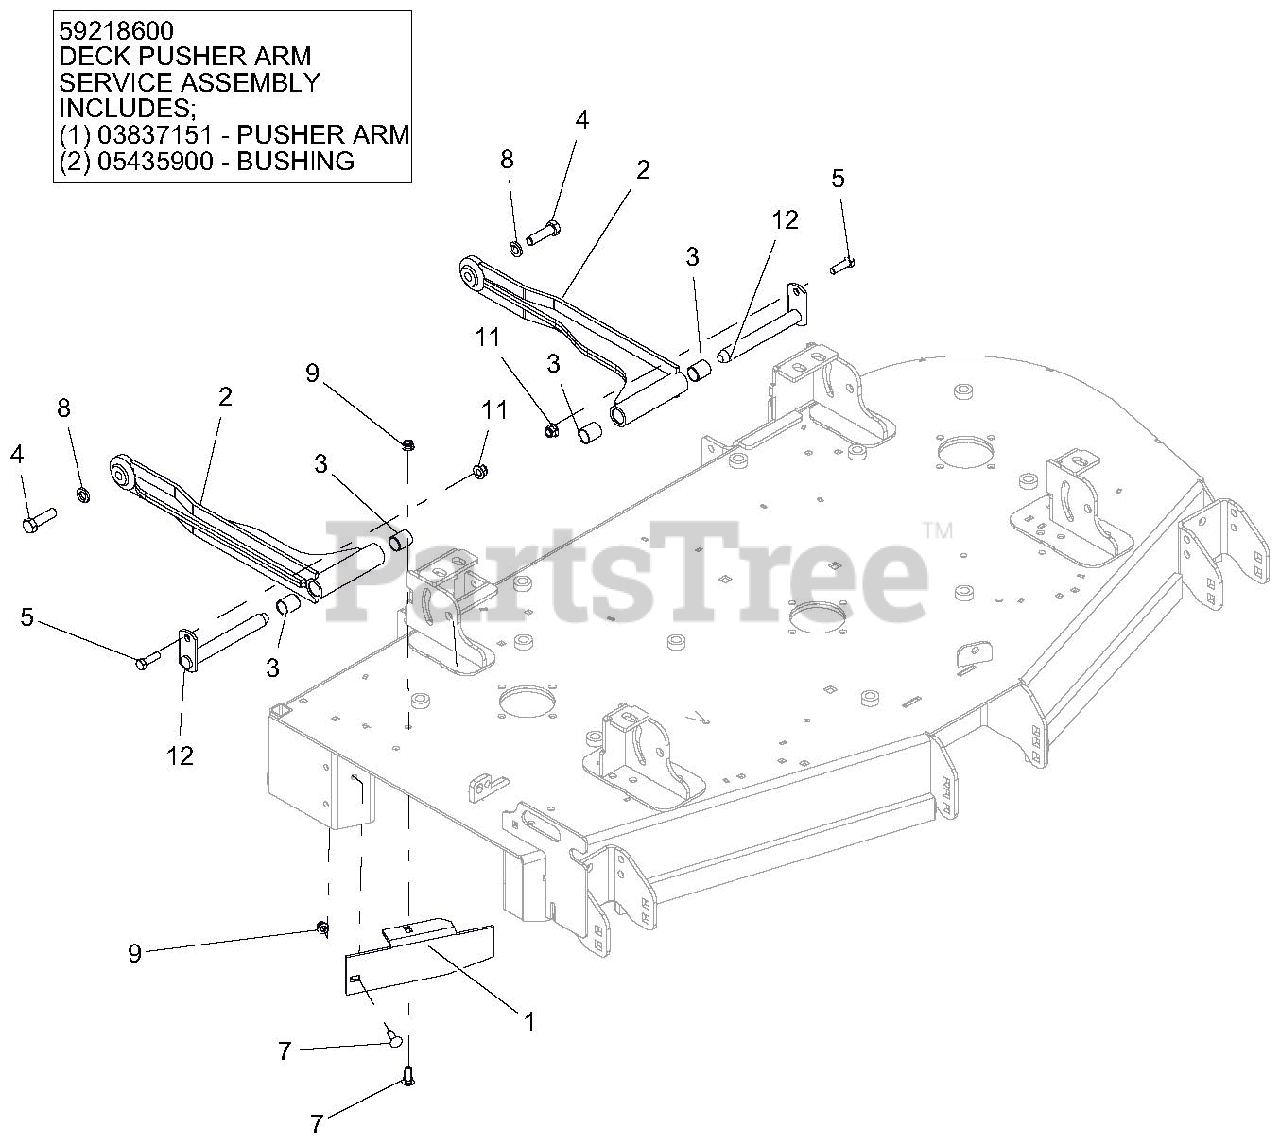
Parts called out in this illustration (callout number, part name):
1	BAFFLE, 52" DISCHARGE
2	WMT, DECK STABILIZER ARM
3	BRG, .750 X .875 X 1.000
4	BLT-HEX .50-13X1.75 GR5 YWZC EP80
5	BLT-HEX .38-16X1.25 GR5 YWZC
7	BLT-RDHDSQSHNK .31-18X1.00 G5 Y
8	WSHR-LK .50X.125 REG YWZC
9	NUT-LK-NYL-FLG .31-18 YWZC
11	NUT-LK-NYL-FLG .38-16 YWZC
12	WLDMT, MOWER MTG. PIN
13	DECK PUSHER ARM SERVICE ASSEMBLY
14	PUSHER ARM
15	BUSHING
